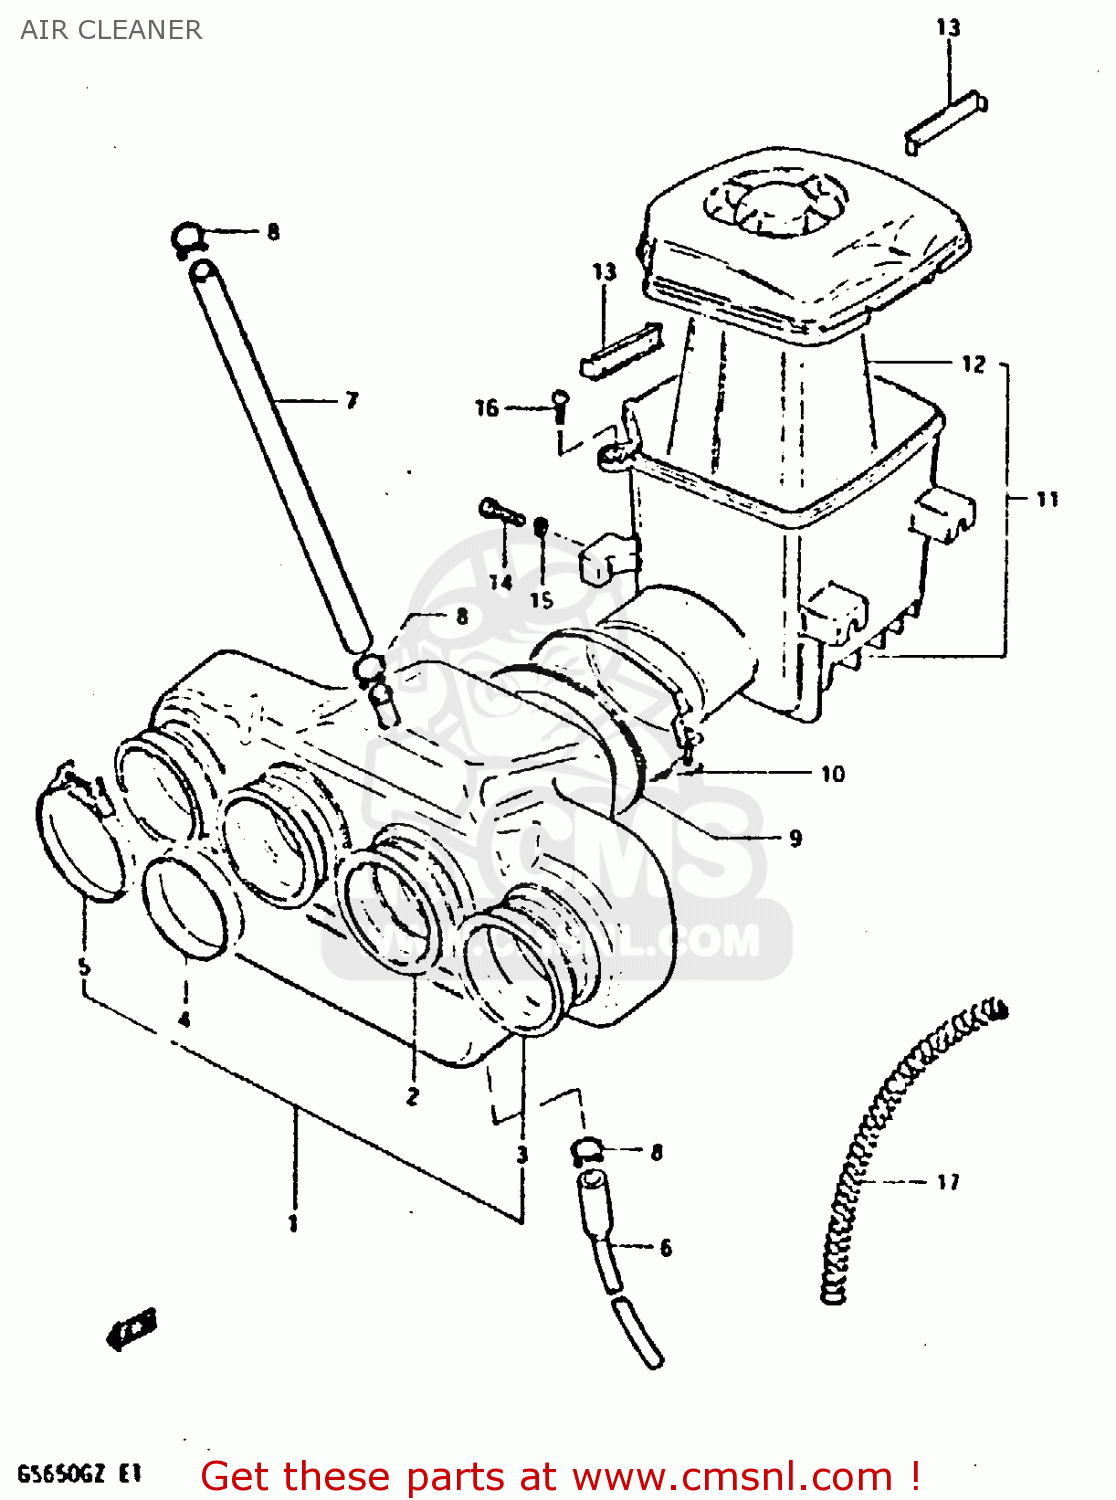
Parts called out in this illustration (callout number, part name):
1	CASE,AIR CLEANER,FRONT
2	TUBE,OUTLET,INNER
3	TUBE,OUTLET OUTER
4	RING,CARBURETOR AIR INLET HOSE
5	CLAMP
6	DRAIN TUBE
7	HOSE
8	CLIP
9	JOINT,HOSE AIR CLEANER
10	CLAMP
11	CLEANER SET,AIR,REAR
12	FILTER ASSY
13	SLIDER
14	BOLT, UPPER
15	LOCK WASHER
16	SCREW
17	SPRING
